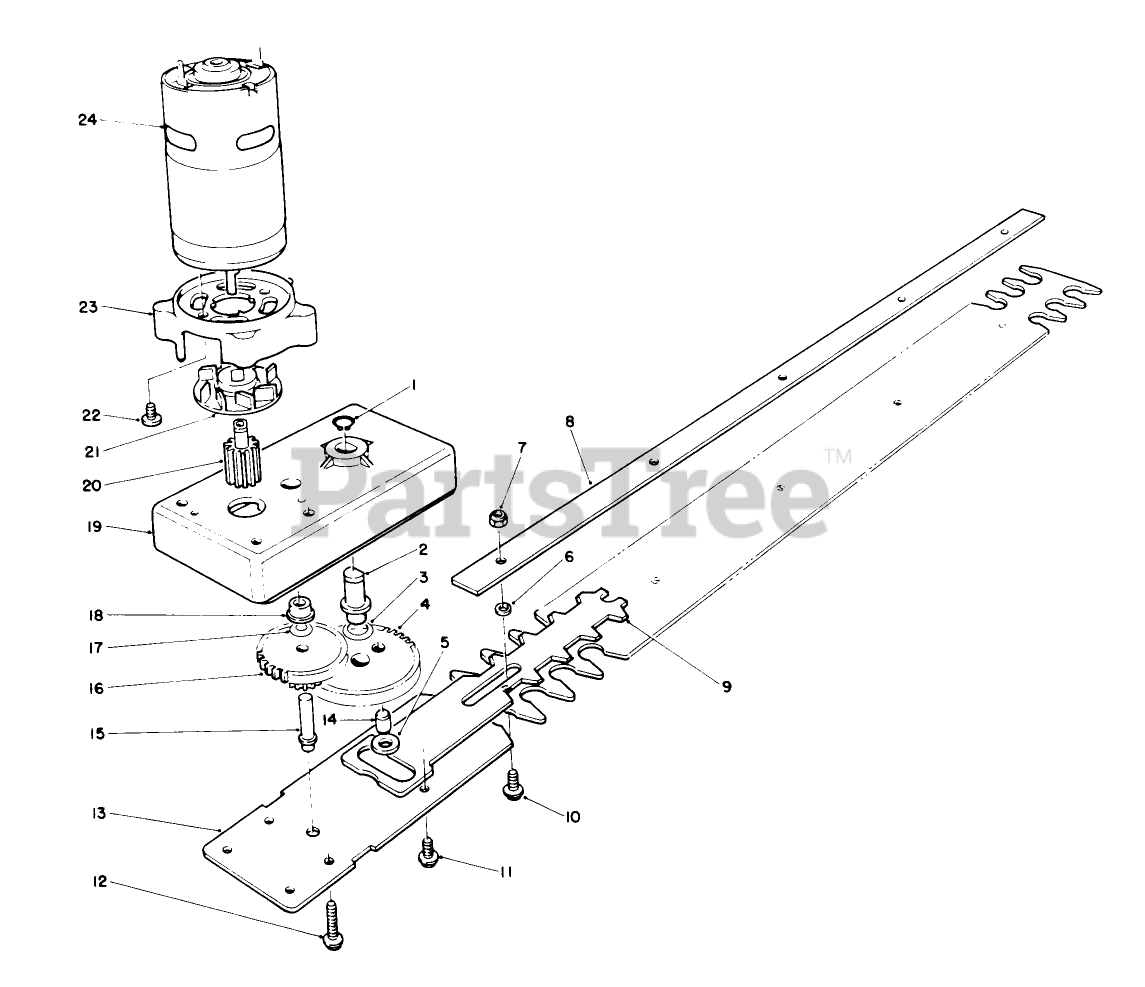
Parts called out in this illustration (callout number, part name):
2	Shaft-Driver
3	WAVE-DRIVER
4	Gear-Drive (Incl. Ref. #14)
5	BUSHING-CAM
6	BLADE-BUSHING
7	NUT-LOCK
8	BLADE-RETAINER
9	BLADE-CUTTING
10	HEX SCREW 8-32X.5
11	SCREW-HWHTF
12	SCREW - #8 X 1-1/4
13	Blade-Bottom
14	Pin-Drive
15	SHAFT-IDLER
16	GEAR-IDLER
17	WAVE-IDLER
18	Bearing-Idler
19	Housing-Gear Assembly (Incl Ref. 2 & 18)
20	Gear-Motor
21	Fan-Motor
22	Screw-Phil. Pan Hd.
23	Support-Motor
24	Motor Assembly (Incl. Ref. #20-23)
